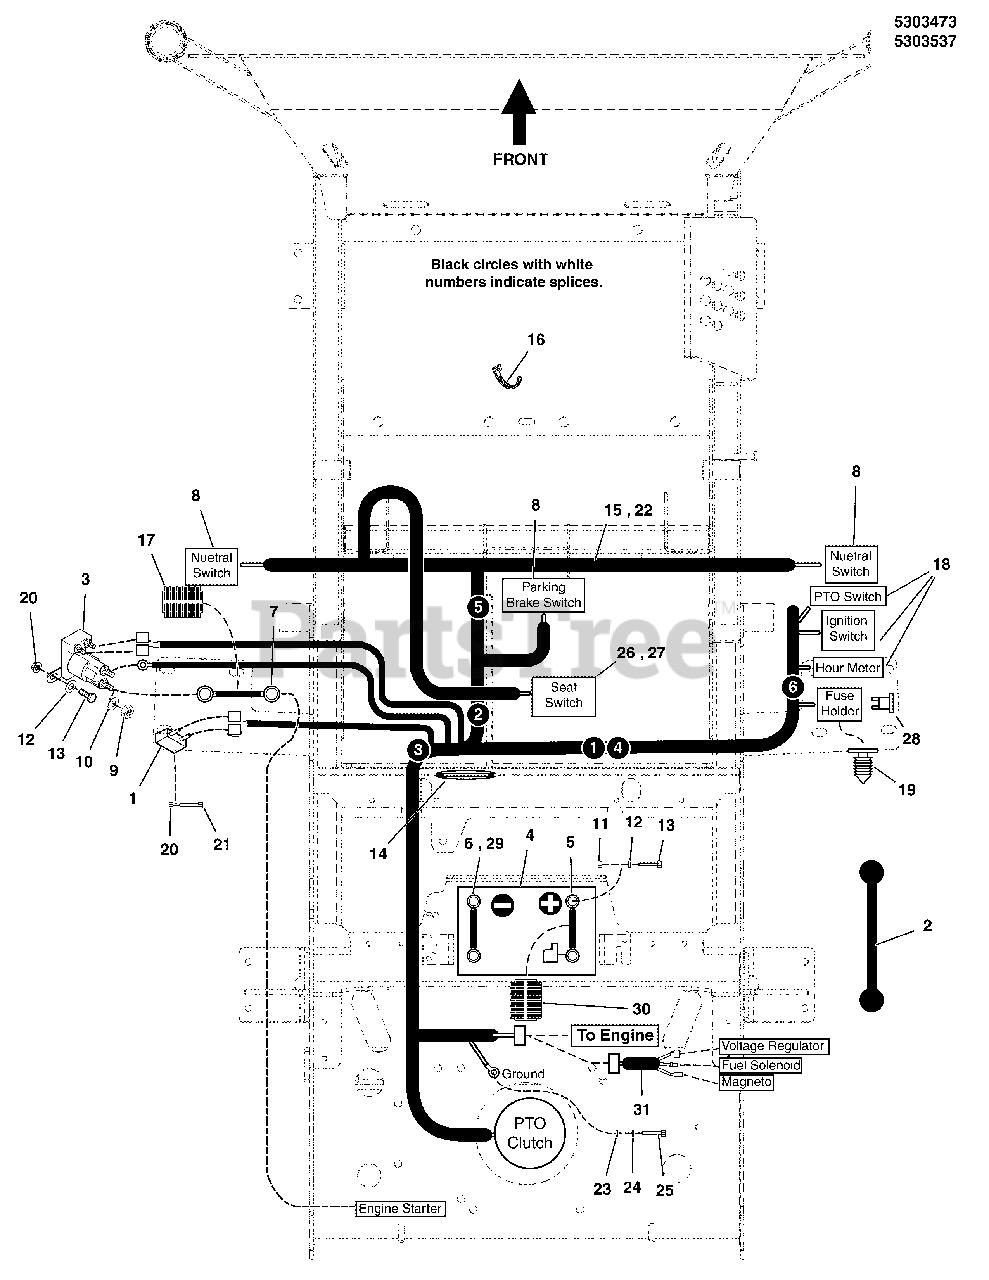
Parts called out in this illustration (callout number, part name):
1	BREAKER-CIRCUIT 12VOLT 20AMPS W/TAB
2	STRAP-BLACK RUBB
3	SOLENOID-4 POLE 12 VOLT DC (TROMBETTA)
4	BATTERY, WET ( BCIU1, 350 CCA)
5	BATTERY CABLE, POS, 15, 1/4-5/16
6	BATTERY CABLE, NEG, 14, 5/16-5/16
7	BATTERY CABLE, POS, 22, 1/4-5/16
8	SWITCH, PLUNGER, NO/NC SNAP-IN
9	NUT, 5/16-24 JAM
10	WASHER, 5/16 LIGHT LOCK
11	NUT, 1/4-20 HEX SERR. FLANGE
12	WASHER, Flat, 1/4
13	BOLT, 1/4-20 X 3/4 GD5 YZ
14	GROMMET, 1-1/2" ID FOR 1/4" METAL
16	TIE, SELF-LOCKING, 12"
17	WIRE LOOM, 3/8 ID X 18 IN
18	SEE INSTRUMENT CONTROL PANEL GROUP
19	FIR TREE MOUNT, PACKARD
20	NUT, Nylock Flanged, 1/4-20
21	SCREW,1/4-20X3/4, ZINC PHOS & OIL
22	WIRE HARNESS, C TURF, WARNER
23	WASHER, 5/16 INT. TOOTH LOCK
24	WASHER, 5/16 SAE
25	BOLT, M8-1.25 X 20MM GD8.8
26	SWITCH, NC, W/ BOLT-IN BASE
27	SWITCH, NC, W/ TWIST-IN BASE
28	FUSE, ATO 15 AMP (SV)
29	BATTERY CABLE, NEGATIVE, 10"
30	WIRE LOOM, 3/8 ID X 12"
31	WIRE HARNESS, JUMPER, KAWI
